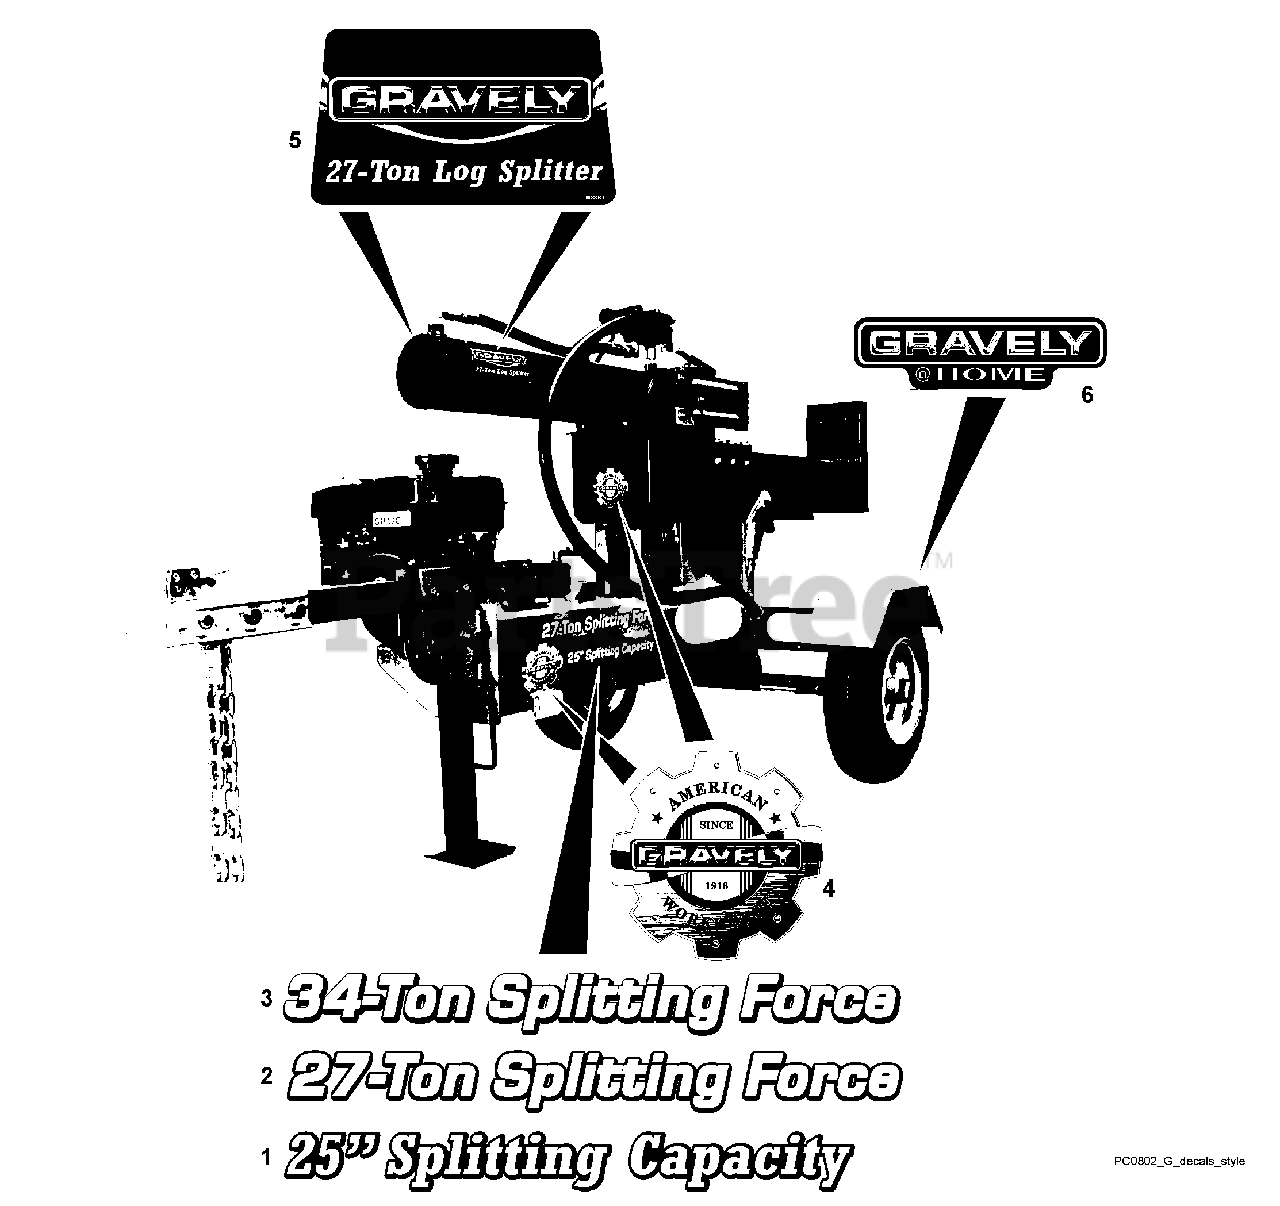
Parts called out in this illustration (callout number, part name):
1	Decal, Log Splitter 25" Length
2	Decal, Log Splitter – 27T – Gravely (917003)
3	Decal, Log Splitter – 34T – Gravely (917004)
4	Decal, Gravely Heritage, Large
5	Decal, Splitter, Gravely 27T (917003)
6	Decal, Gravely
